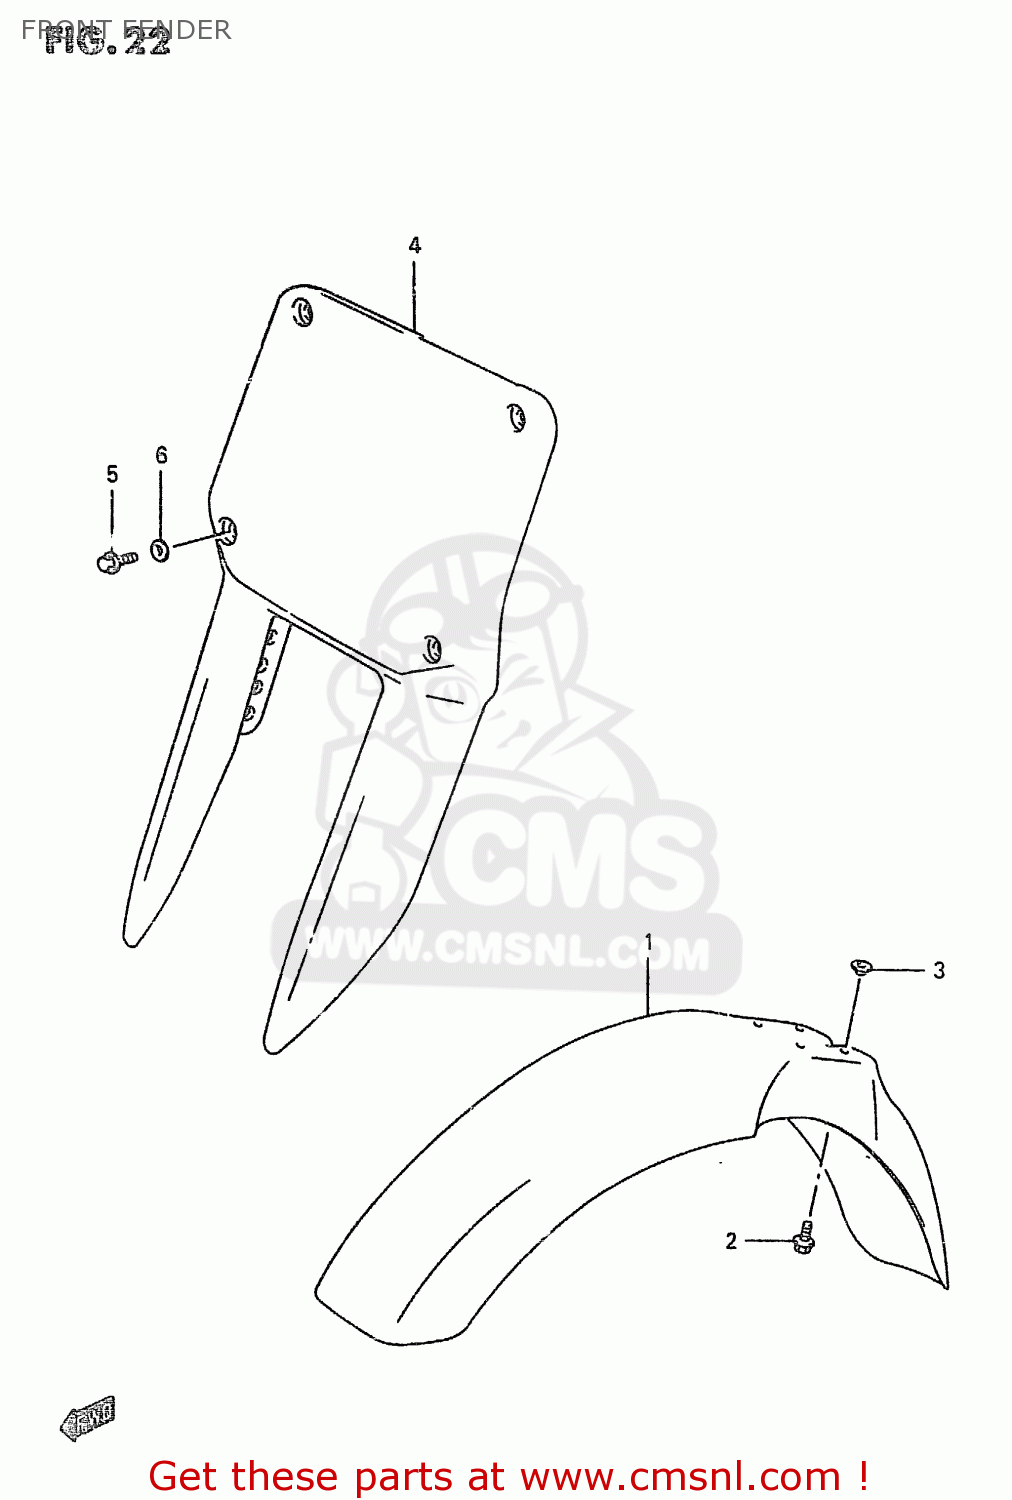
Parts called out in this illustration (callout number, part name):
1	FENDER,FRONT
2	BOLT(6X16)
3	WASHER
4	PLATE,NUMBER FR
5	BOLT
6	WASHER
